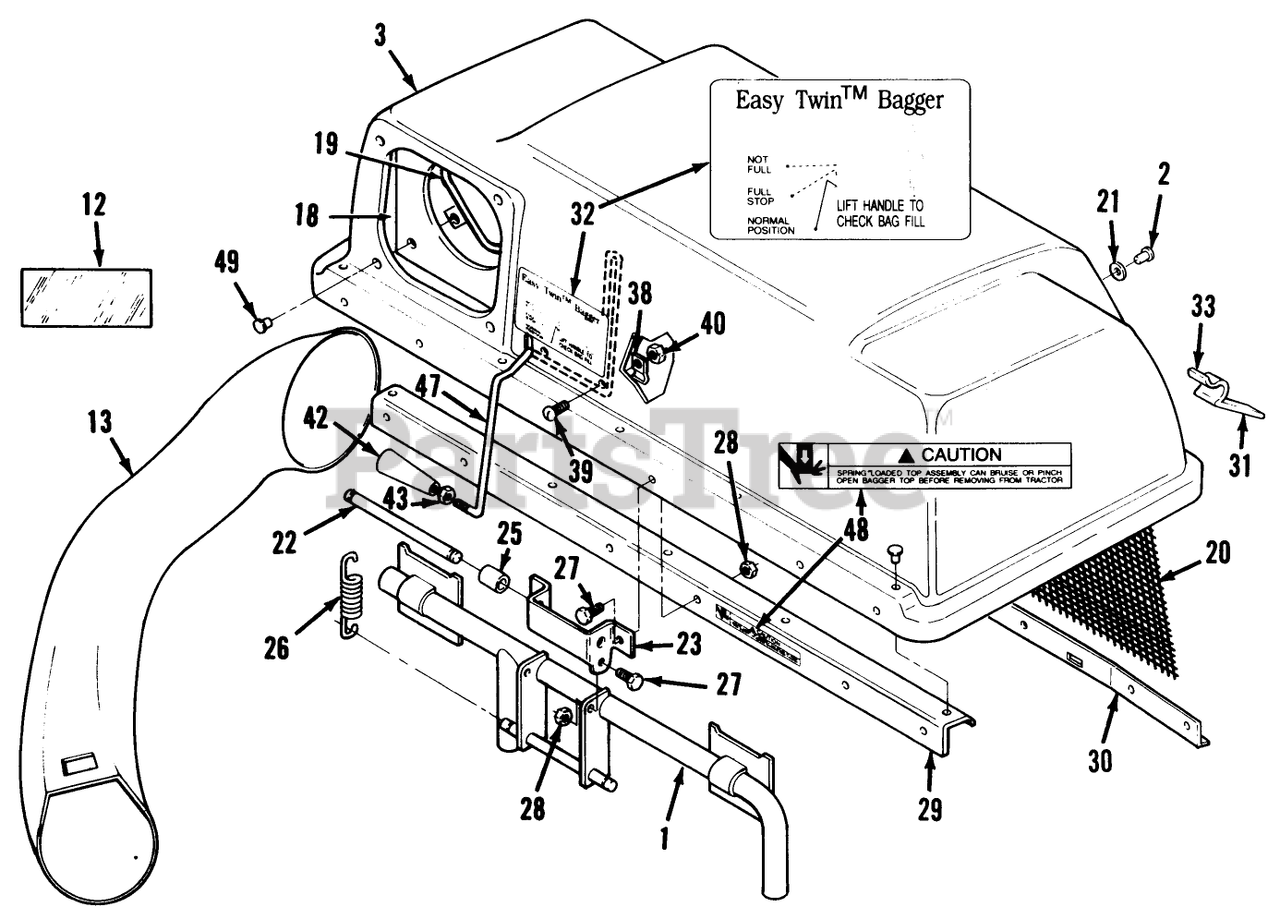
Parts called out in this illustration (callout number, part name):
1	FRAME ASM
2	RIVET-BLIND
3	TOP-BAGGER
12	DECAL-OVERLAY
13	CHUTE-BAGGER (C)
18	SEAL-CHUTE
19	CLAMP-SEAL
20	SCREEN-BAGGER
21	Washer
22	PIN-SPRING
23	HINGE-BAG TOPB
25	SPACER
26	SPRING-EXTENSION
27	SCREW-HH
28	NUT-LOCK, NI
29	Bagger-Stiffener
30	SUPPORT-SCREEN B
32	DECAL
33	Latch-Bag
38	Clip
39	Screw
40	NUT-LOCK, NI
42	HANDLE-TAPERED
43	NUT-JAM
47	FEELER-FILL, BAG
48	DECAL-CAUTION
49	Pop Rivet
